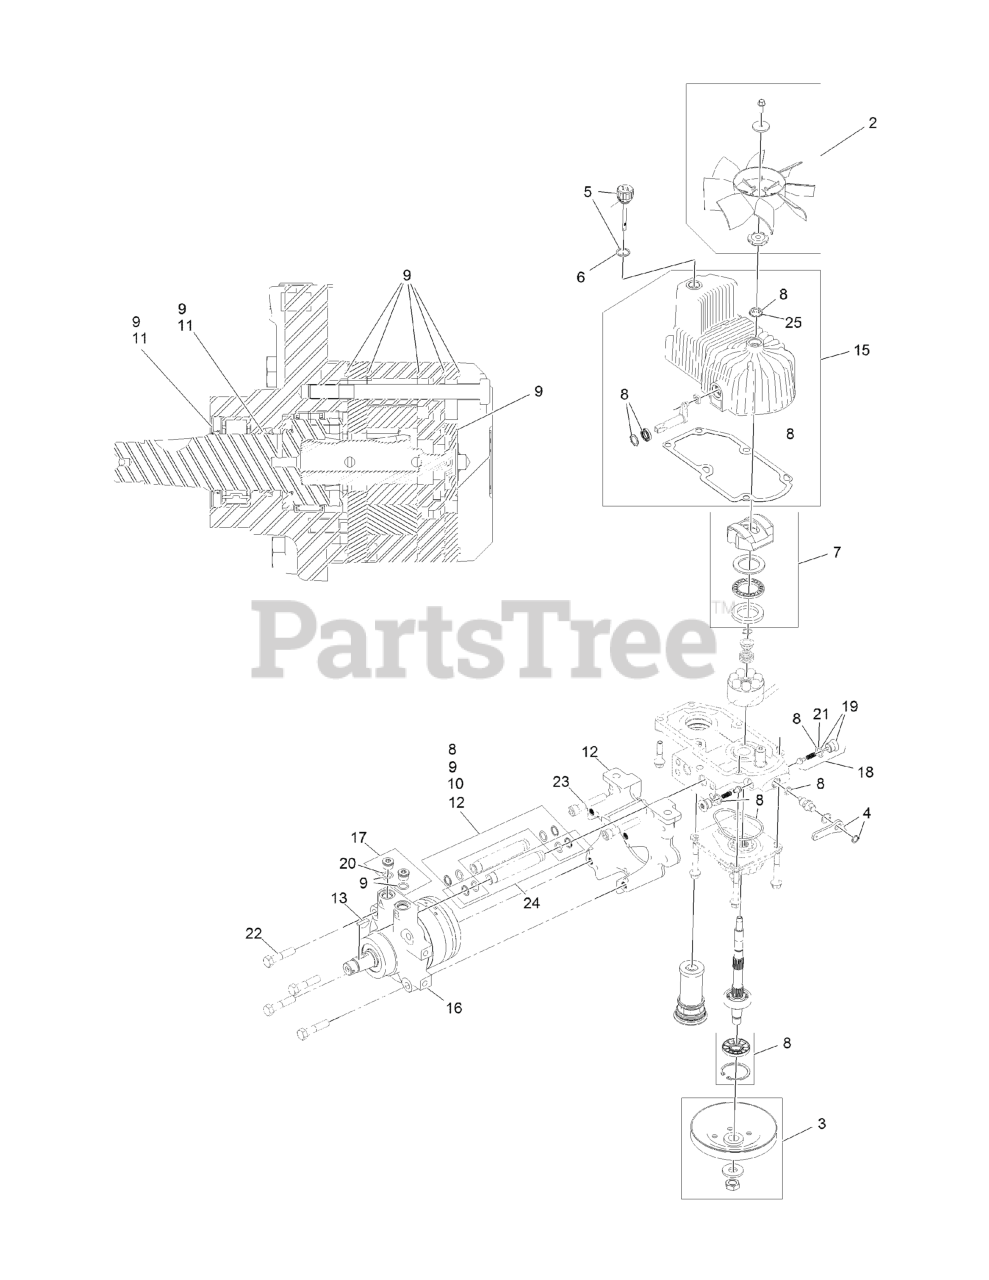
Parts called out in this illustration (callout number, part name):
2	FAN KIT
3	PULLEY KIT
4	HANDLE-BYPASS VALVE, HYDRO
5	DIPSTICK-HYDRO W/GASKET
6	GASKET-DIPSTICK, HYDRO
7	SWASH BLOCK KIT
8	PUMP SEAL KIT
9	MOTOR SEAL KIT
10	TUBE SEAL KIT
11	OUTPUT SHAFT SEAL KIT
12	NOSE CUP-UHT
13	KEY-WOODRUFF
15	HOUSING-HYDRO, LH
16	MOTOR-HYDRAULIC LH 240CC
17	MAGNETIC PLUGS SERVICE KIT
18	CHECK VALVE ASM
19	PLUG-CHECK (W/O-RING)
21	O-RING-CHECK VALVE
22	SCREW HH
23	SCREW-HSH
24	HYDRAULIC TUBE KIT
25	SEAL-FAN DRIVE
26	PULLER-PULLEY
27	ROTATING KIT
